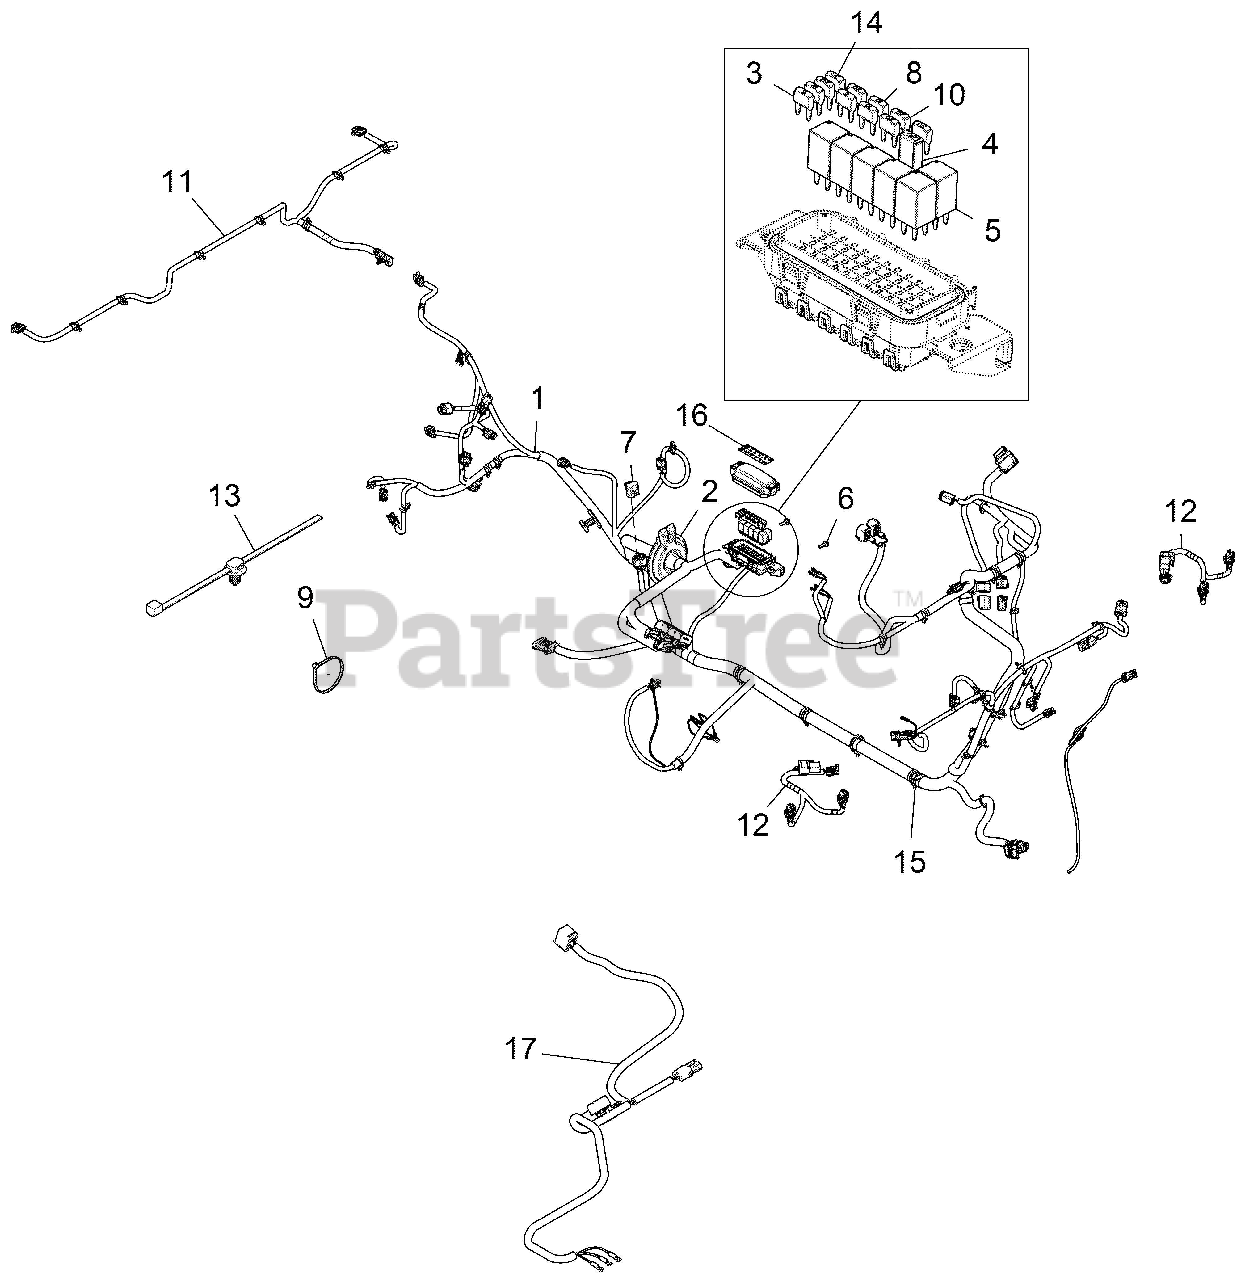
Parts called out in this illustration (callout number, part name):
1	HARNESS-CHASSIS,570,EPS
2	GROMMET-CHASSIS HARNESS
3	FUSE-5A,MINI BLADE
4	BREAKER-CIRCUIT,20 AMP
5	RELAY-SPST,SERIES 303,SEALED
6	SCR-HXFL-M6X1.0X20 8.8 RIE
7	COVER-DIAGNOSTIC,W/CLIP
8	FUSE,IGN.10 AMP,(10)
9	CABLE TIE (10)
10	FUSE,PARK,20 AMP,(10)
11	HARNESS-BOX-ARIENS SPLY
12	HARNESS-HEADLIGHT,ARIENS
13	CLIP-ROUTING
14	FUSE,MAIN,30 AMP,(10)
15	CLIP-ROUTING
16	DECAL, RELAY/FUSE BLOCK
17	HARNESS-BOX,LIFT
